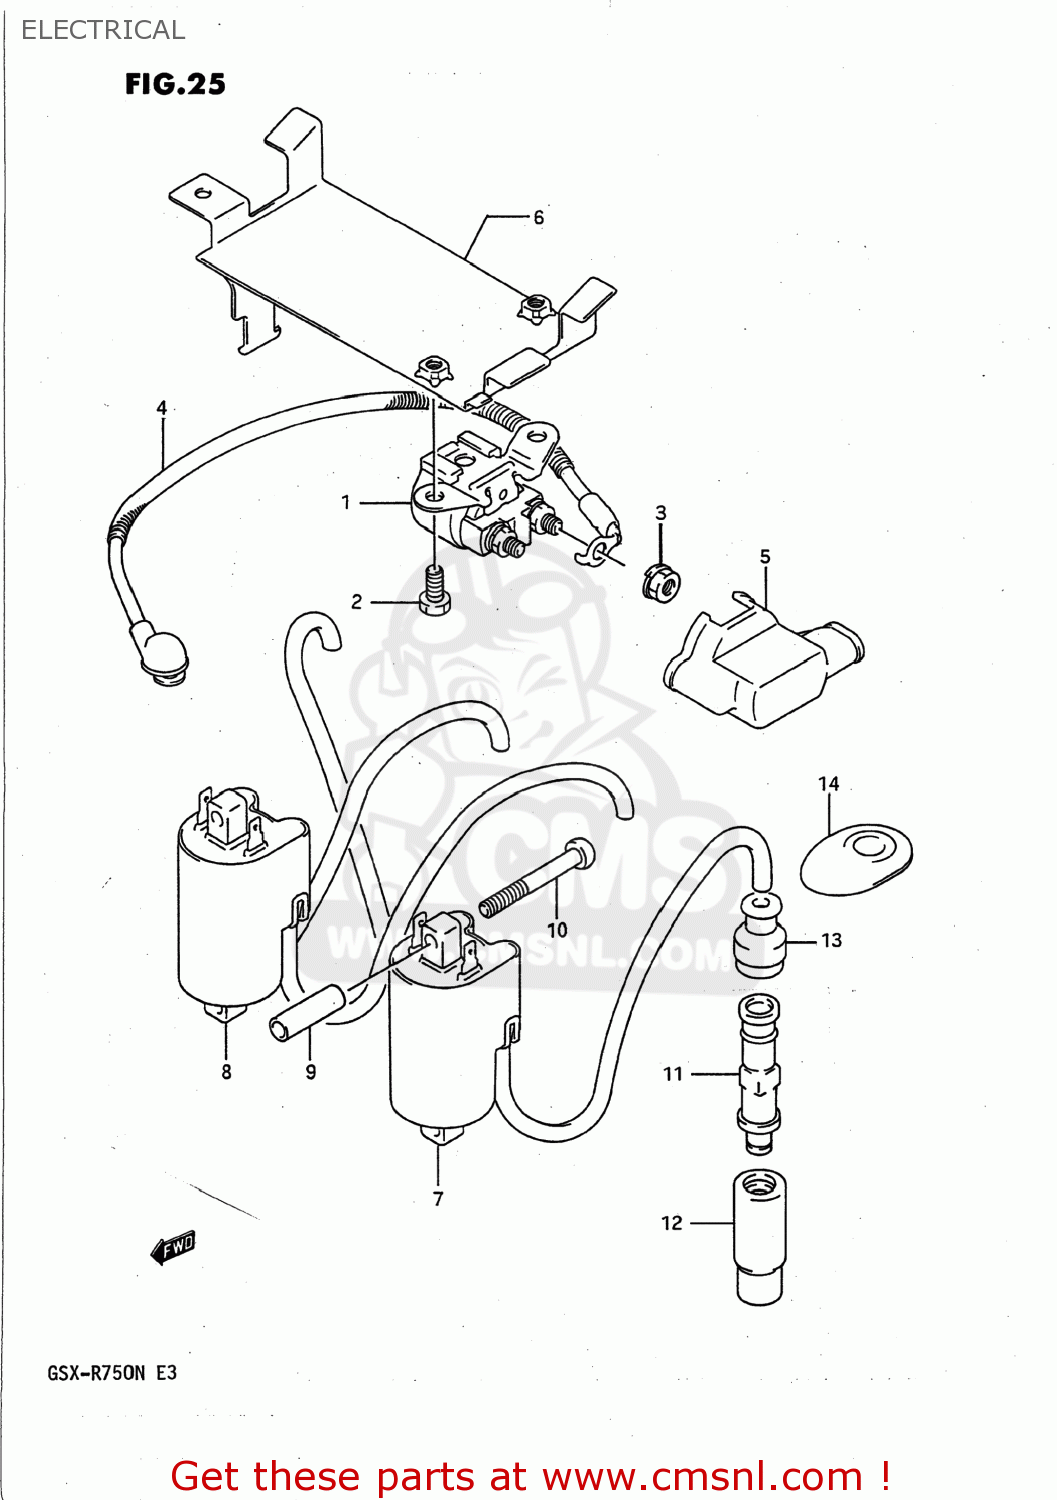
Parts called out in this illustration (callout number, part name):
1	RELAY ASSY,STARTING MOTOR
2	SCREW(6X8)
3	NUT
4	WIRE,STARTER MOTOR
5	CAP,STARTER RELAY
6	HOLDER COMP,ELECTRONIC PARTS
7	COIL ASSEMBLY,IGNITION (1-4)
8	COIL ASSEMBLY,IGNITION
9	SPACER (6.5X10.5X31.7)
10	SCREW
11	CAP,SPARK PLUG
12	SEAL,SPARK PLUG
13	SEAL,HIGH TENSION CORD
14	COVER,SPARK PLUG CAP
